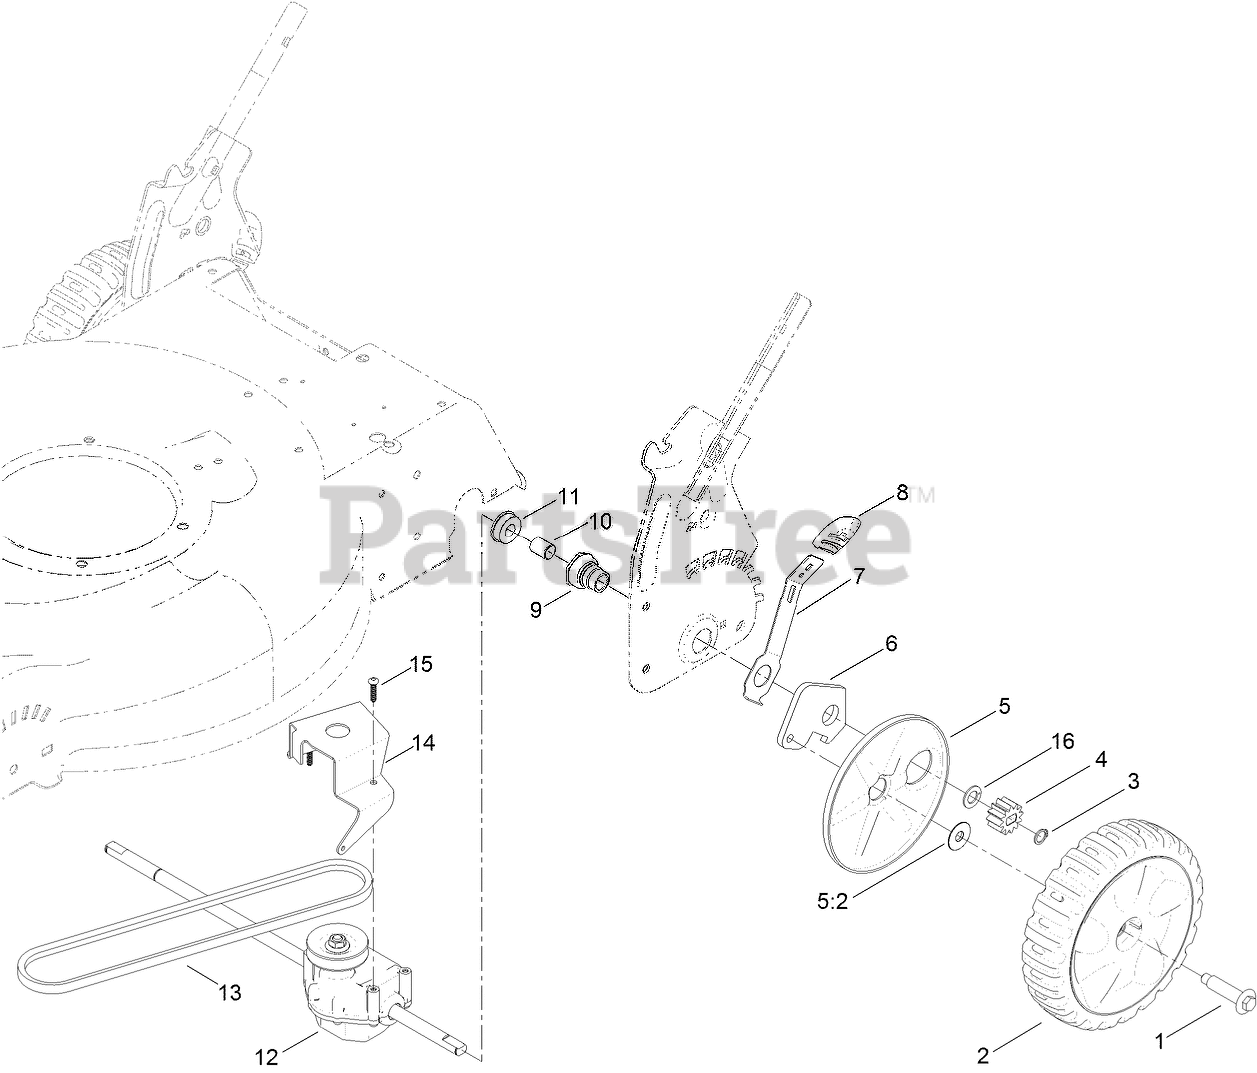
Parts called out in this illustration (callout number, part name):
1	BOLT-SHOULDER
2	8 INCH WHEEL AND GEAR ASM
3	RING-RETAINING
4	GEAR-PINION
5	WHEEL COVER ASM
5:2	WASHER-STEPPED
6	ARM-PIVOT, REAR
7	ARM-SPRING
8	Knob-Lever, HOC
9	RETAINER-BUSHING, HOC
10	BUSHING-SLEEVE
11	BEARING-BALL
12	TRANSMISSION ASM
13	V-BELT
14	BRACKET-TRANSMISSION
15	SCREW-PLASTITE
16	WASHER-THRUST
